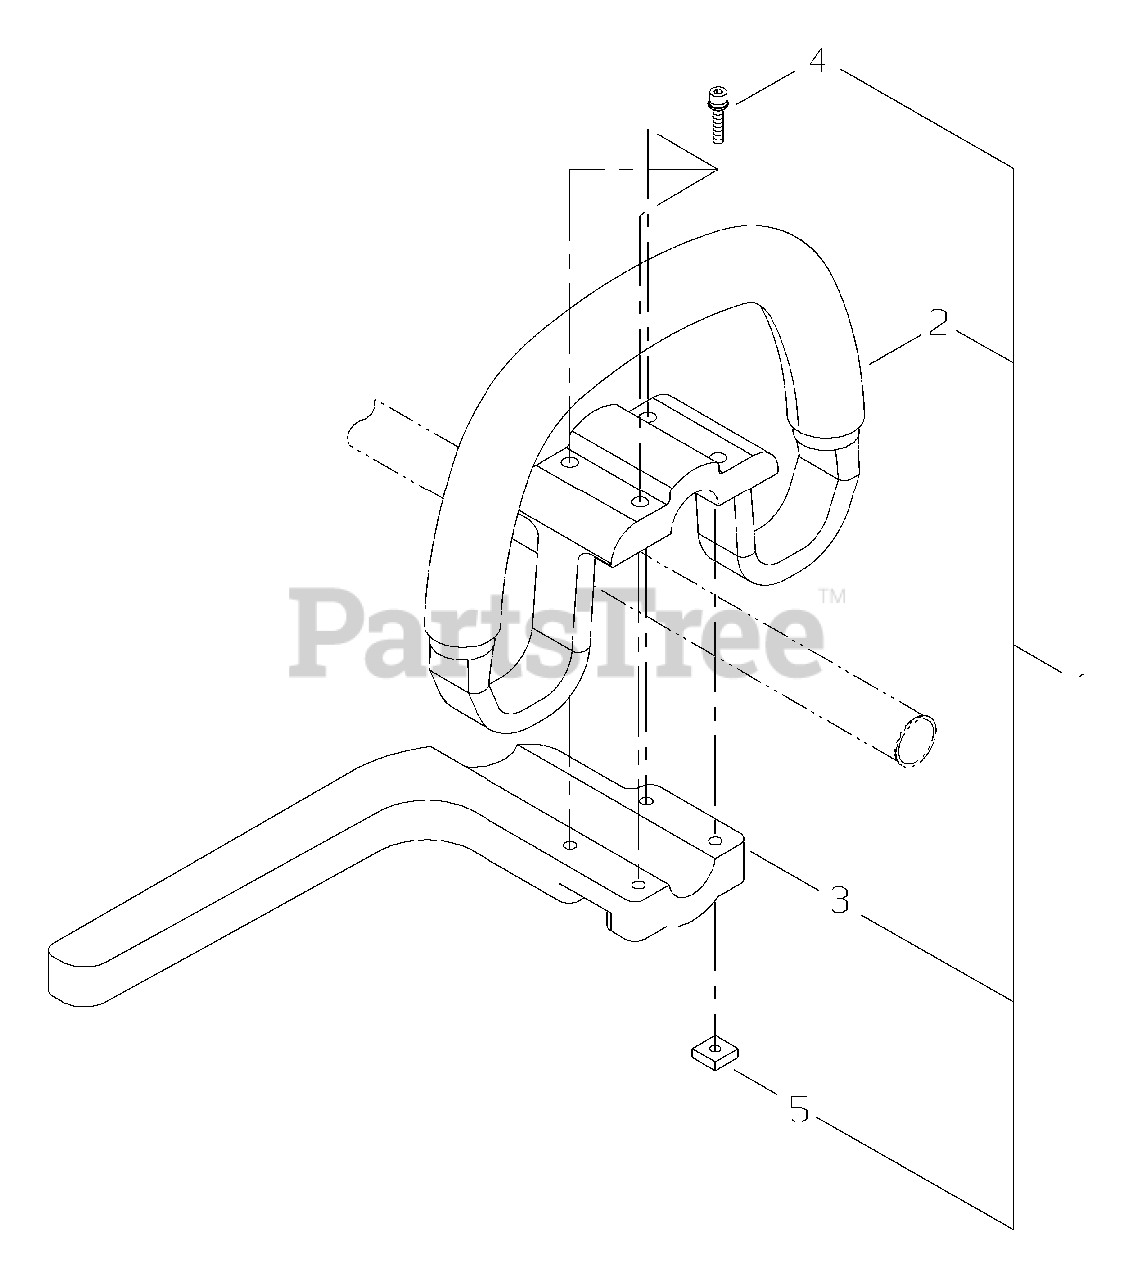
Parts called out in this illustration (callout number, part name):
1	HANDLE KIT, FRONT
2	HANDLE, FRONT
3	BRACKET, HANDLE
4	BOLT M5×35
5	NUT M5
